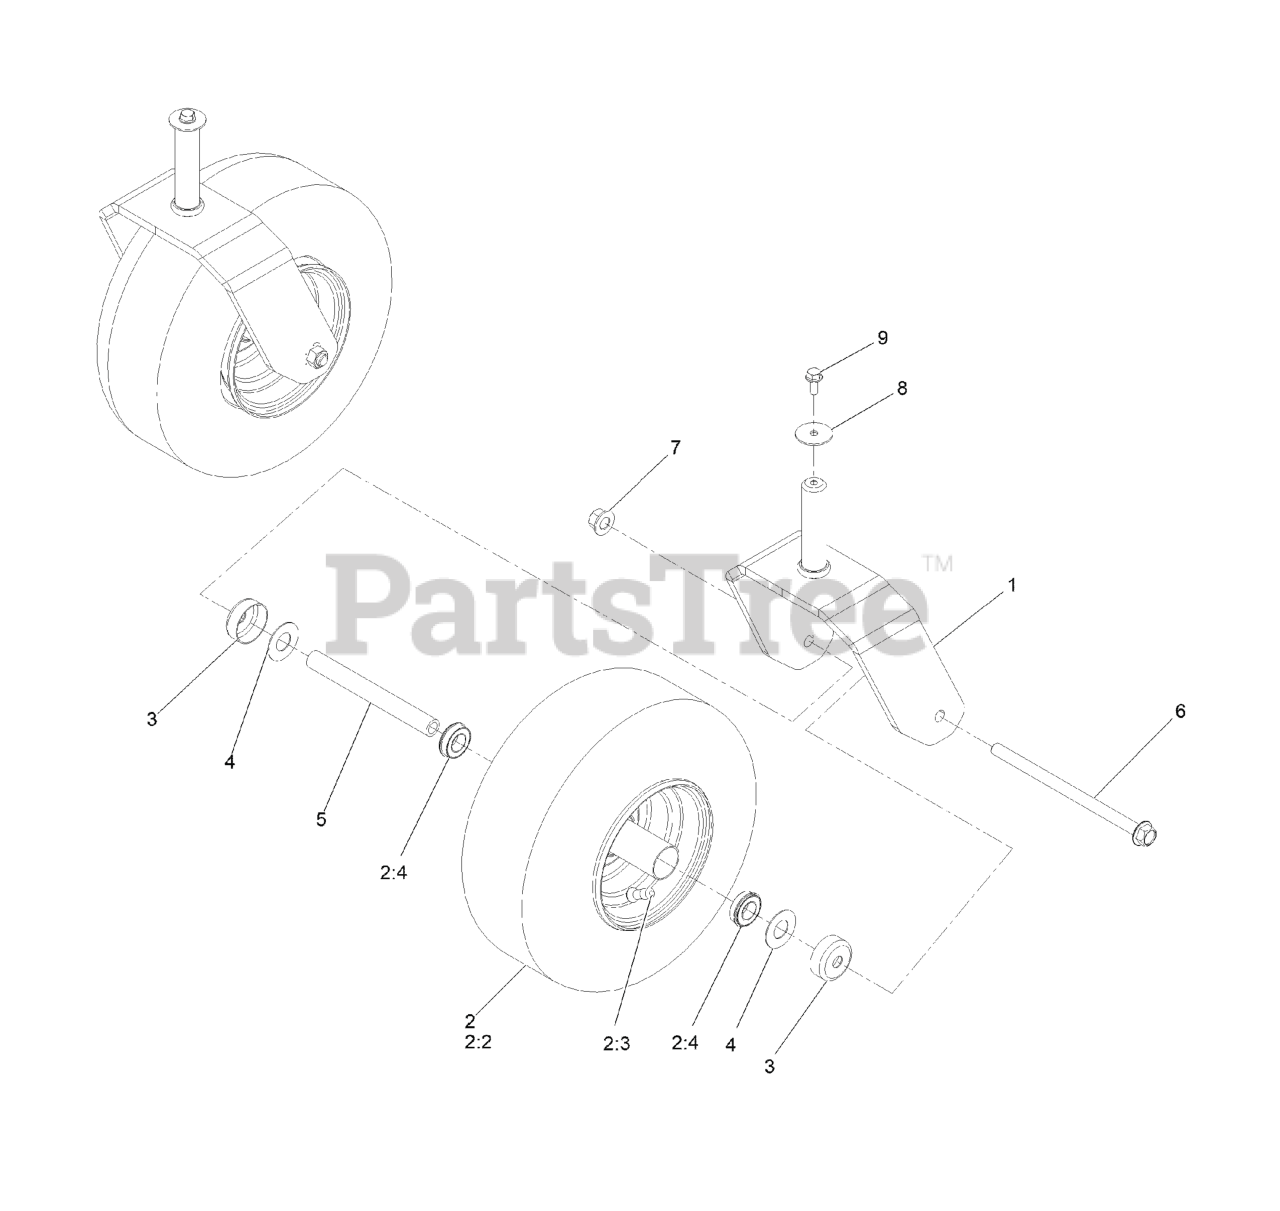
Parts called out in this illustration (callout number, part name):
2	TIRE AND WHEEL ASM
2:3	Stem-Valve
2:4	BEARING
3	GUARD-SEAL
5	SPANNER-WHEEL
6	SCREW-HHF
7	Nut-Lock 1/2-13
8	WASHER-FLAT
9	SCREW-HHF
